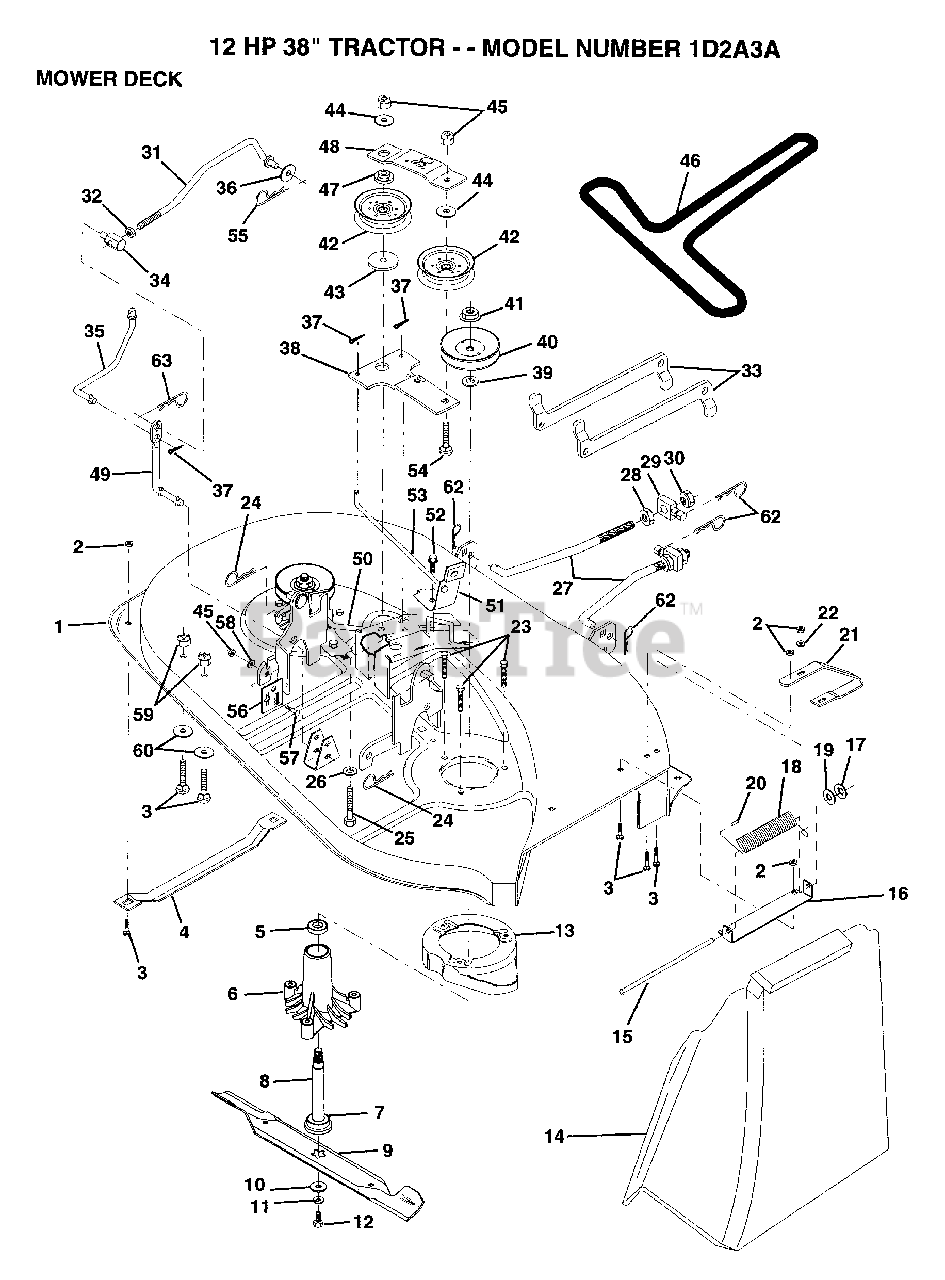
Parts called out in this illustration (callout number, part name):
3	BOLT
4	RUNNER-LH M
5	BEARING
6	HSG ASM MANDREL
7	BEARING.BALL
9	"BLADE.38"" HIPERF"
10	WASHER BLADE
12	BLADE BOLT
14	DEFLECTOR-SHLD T
15	ROD-HINGE T
16	BRKT DEFLECTOR
17	NUT PUSH M
18	SPRING TORSION
19	WASHER
20	CAP-SLEEVE LT
21	RUNNER RH
22	WASHER M
25	BOLT
26	WASHER GT
27	"LINK ASM.,FRONT"
28	NUT
29	TRUNION
30	NUT.LK.W/WSH.1/2.
31	CLUTCH ROD PRI
32	NUT
33	SUSP ARM REAR
34	TRUNNION
35	CLUTCH ROD SEC
36	WASHER
38	IDLER ARM ASSY
39	WASHER
42	FLAT IDLER PULLEY
43	SPACER RETAINER
44	WASHER GT
46	BELT-V.88.12.MW
47	RETAINER SPACER
48	IDLER ARM STIFF
49	PIVOT ROD
50	BRAKE ROD LH
51	BRAKE ASM
52	SCREW
53	BRAKE ROD RH
54	BOLT
55	SPRING.RETAINER
56	PLATE ADJ LINK LH
57	BOLT
58	WASHER T
59	NUT
60	WASHER.34X.68X16
62	RETAINER.SPRING
63	RETAINER M
